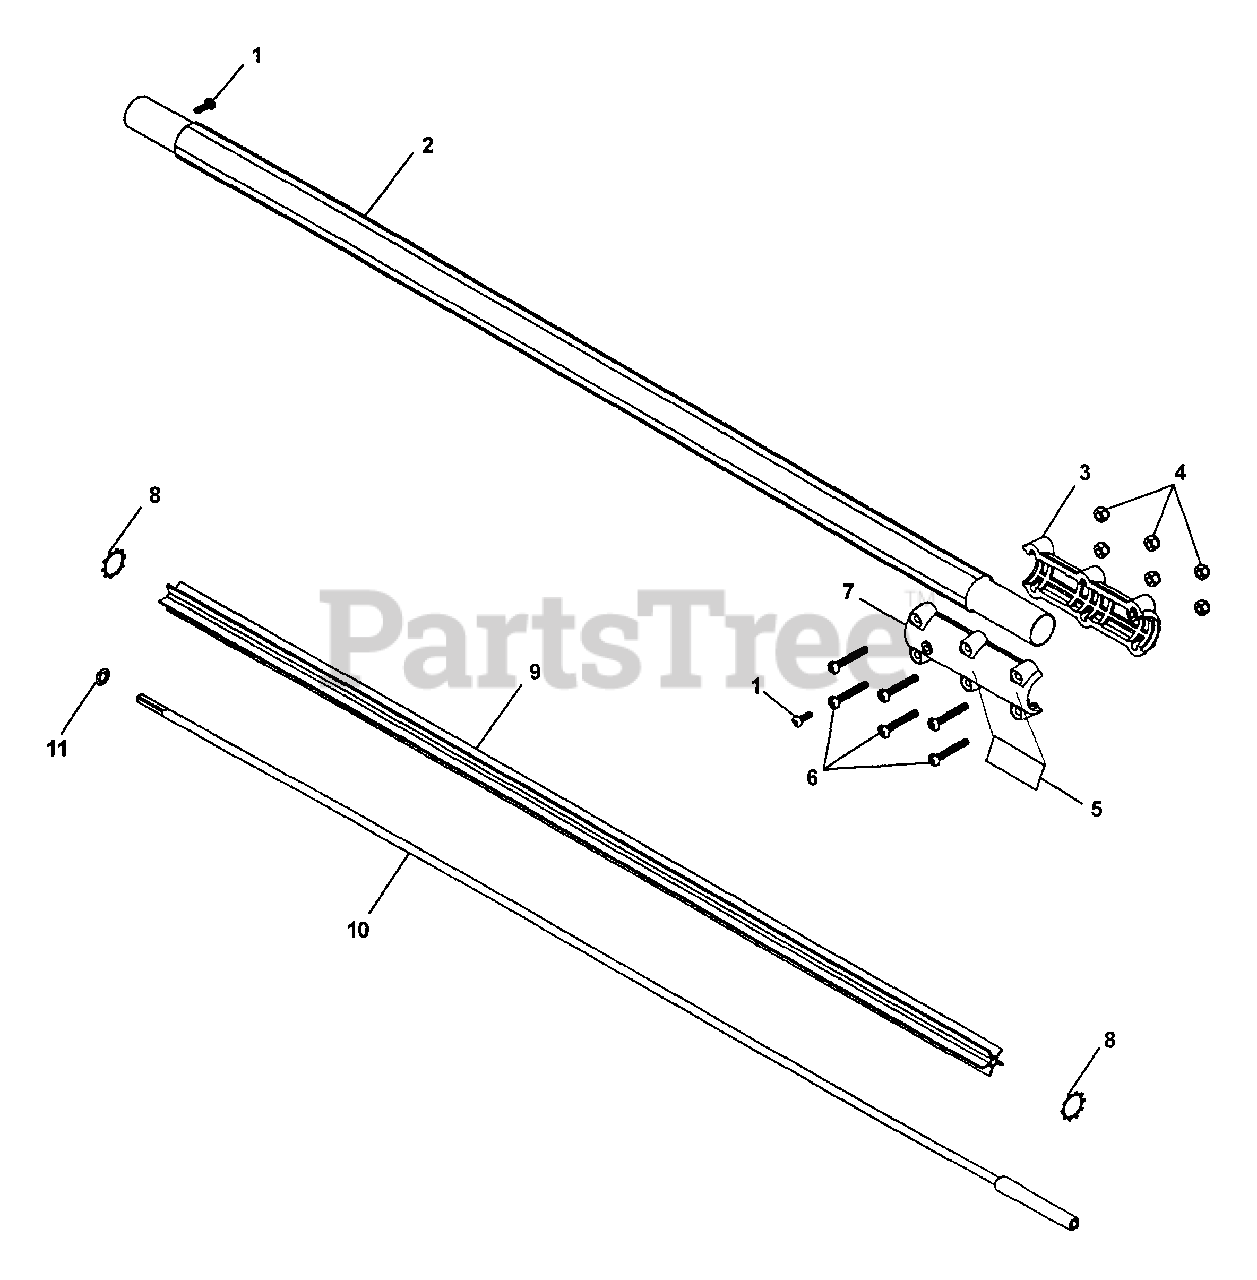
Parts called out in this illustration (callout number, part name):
1	SCREW
2	PIPE, MAIN
3	COLLAR, MAIN PIPE
4	LOCKNUT - 10-24
5	LABEL - CAUTION
6	SCREW - 10-24 X 1-1/4"
7	COLLAR, MAIN PIPE
8	LOCKWASHER - EXTERNAL
9	LINER - FLEXIBLE
10	DRIVESHAFT
11	LOCKWASHER - INTERNAL
